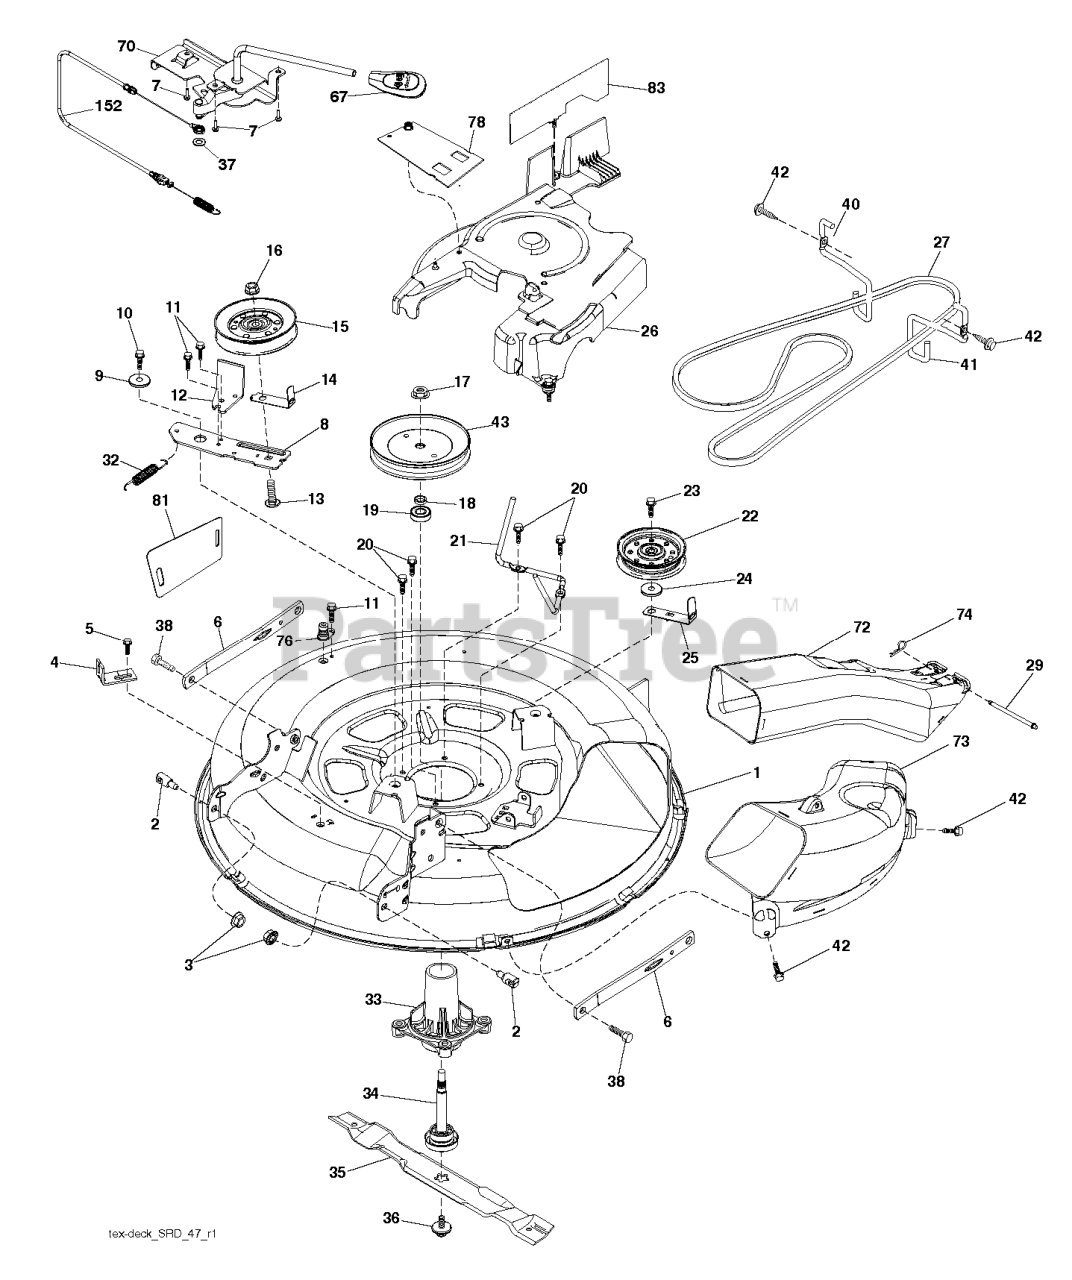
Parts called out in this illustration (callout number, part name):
1	DECK.WELDMENT.30"SRD.BLACK
2	STUD.FASTNER.W/ANTI-ROTATE
3	NUT LOCK HEX FLANGE 5/16-18
4	BRACKET.CLUTCH.CABLE
5	BOLT.5/16HEX.WHS.HD
6	ARMS.SUSP.MOWER.REAR.SRD
7	SCREW.#10 X 0.750.BOS
8	ARM.IDLER.30"SRD
9	SPACER.RETAINER
10	SCREW 3/8-16X1
11	SCREW.1/4-20X5/8
12	RP ARM.BRAKE.MOWER.38"LH.TEX
13	BOLT.3/8-16X1.50
14	KEEPER, BELT IDLER
15	PULLEY.IDLER.4.25
16	NUT LOCK FLG 3/8-16 UNC
17	NUT.FLANGE.LOCK.TOP
18	WASHER.SPACER.MANDREL
20	SCREW, WASHER HEAD
21	KEEPER.BELT.MANDREL.30"
22	PULLEY.IDLER.FLAT.UNPLATED
23	SCREW LT
24	WASHER
25	KEEPER.BELT.30"SRD
26	COVER.ASM.MANDREL.30"
27	V-BELT.DRIVE.MOWER.30"
29	PIN.HINGE.30".SRD
32	SPRING RETURN
33	RP.HOUSING.MANDREL.4PT.
34	SHAFT.ASM.MDRL.N/GREASE.38
35	BLADE.MOWER.BAGGING.30"
36	BOLT.WASHER.ASM.7/16-2
37	WASHER
38	BOLT.SHOULDER
40	KEEPER.BELT.ENGINE.LH.LT.SRD
41	KEEPER.BELT.ENGINE.RH.LT.SRD
42	SCREW, 3/8-16X3/4
43	PULLEY, MANDREL 6.5 PD
67	HANDLE.CLUTCH.CABLE.LT
70	CLUTCH.ASM.MANUAL.LT.PRED
72	CHUTE.UPPER.SRD.30R"
73	CHUTE.LOWER.SRD.30R"
74	RETAINER-SPRNG RB
76	PORT.WASHOUT
78	GUARD ARM CLUTCH
81	SHIELD SUSPENSION
152	CLUTCH CABLE
